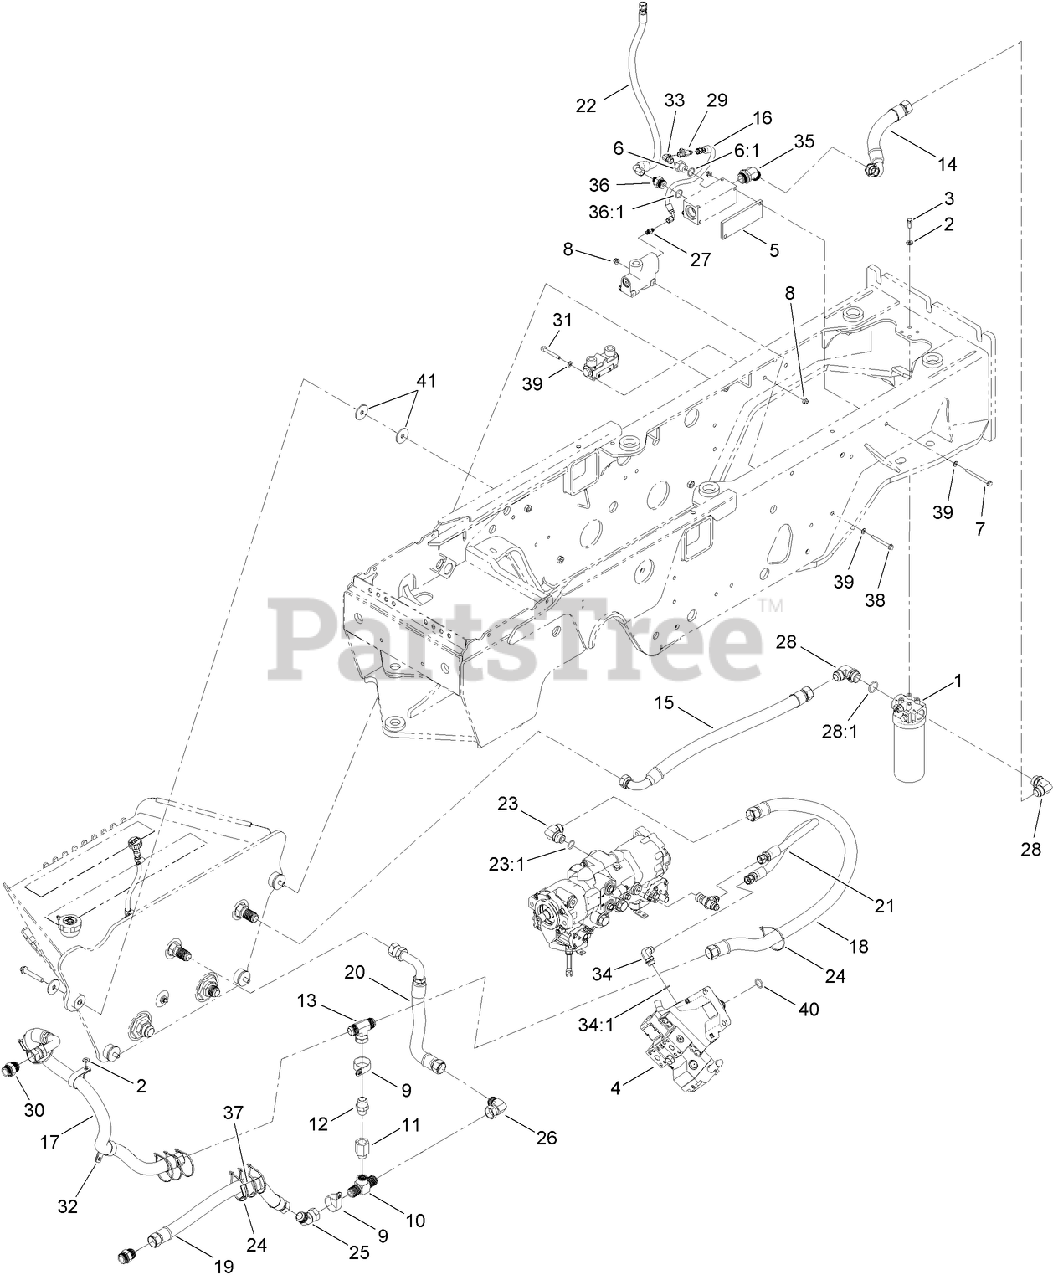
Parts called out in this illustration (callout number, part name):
1	OIL FILTER ASM
2	WASHER-FLAT
3	SCREW-HH
4	MOTOR ASM
5	SPACER
6	ADAPTER-STRAIGHT
6:1	O-RING
7	SCREW-HHF
8	NUT-LOCK, HHF
9	CLAMP-R
10	FITTING-TEE
11	VALVE-CHECK
12	ADAPTER
13	FITTING-TEE
14	HOSE ASM
15	HOSE ASM
16	HOSE ASM
17	HOSE ASM
18	HOSE ASM
19	HOSE ASM
20	HOSE ASM
21	HOSE ASM
22	HOSE ASM
23	FITTING-ELBOW, 90
23:1	O-RING
24	TIE-CABLE
25	FITTING-ELBOW, 45
26	FITTING-ELBOW, 90
27	FITTING-STRAIGHT
28	ELBOW-90 DEG
28:1	O-RING
29	FITTING-HYD, TEE
30	FITTING-STRAIGHT
31	SCREW-FLANGE
32	CLAMP-R
33	ELBOW-SWIVEL, 90 DEG
34	FITTING-ELBOW, 90 DEG
34:1	O-RING
35	FITTING-ELBOW, 45
36	FITTING-STRAIGHT
36:1	O-RING
37	PROTECTOR-HOSE
38	SCREW-HHF
39	WASHER-PLAIN
40	O-RING
41	WASHER-FLAT
